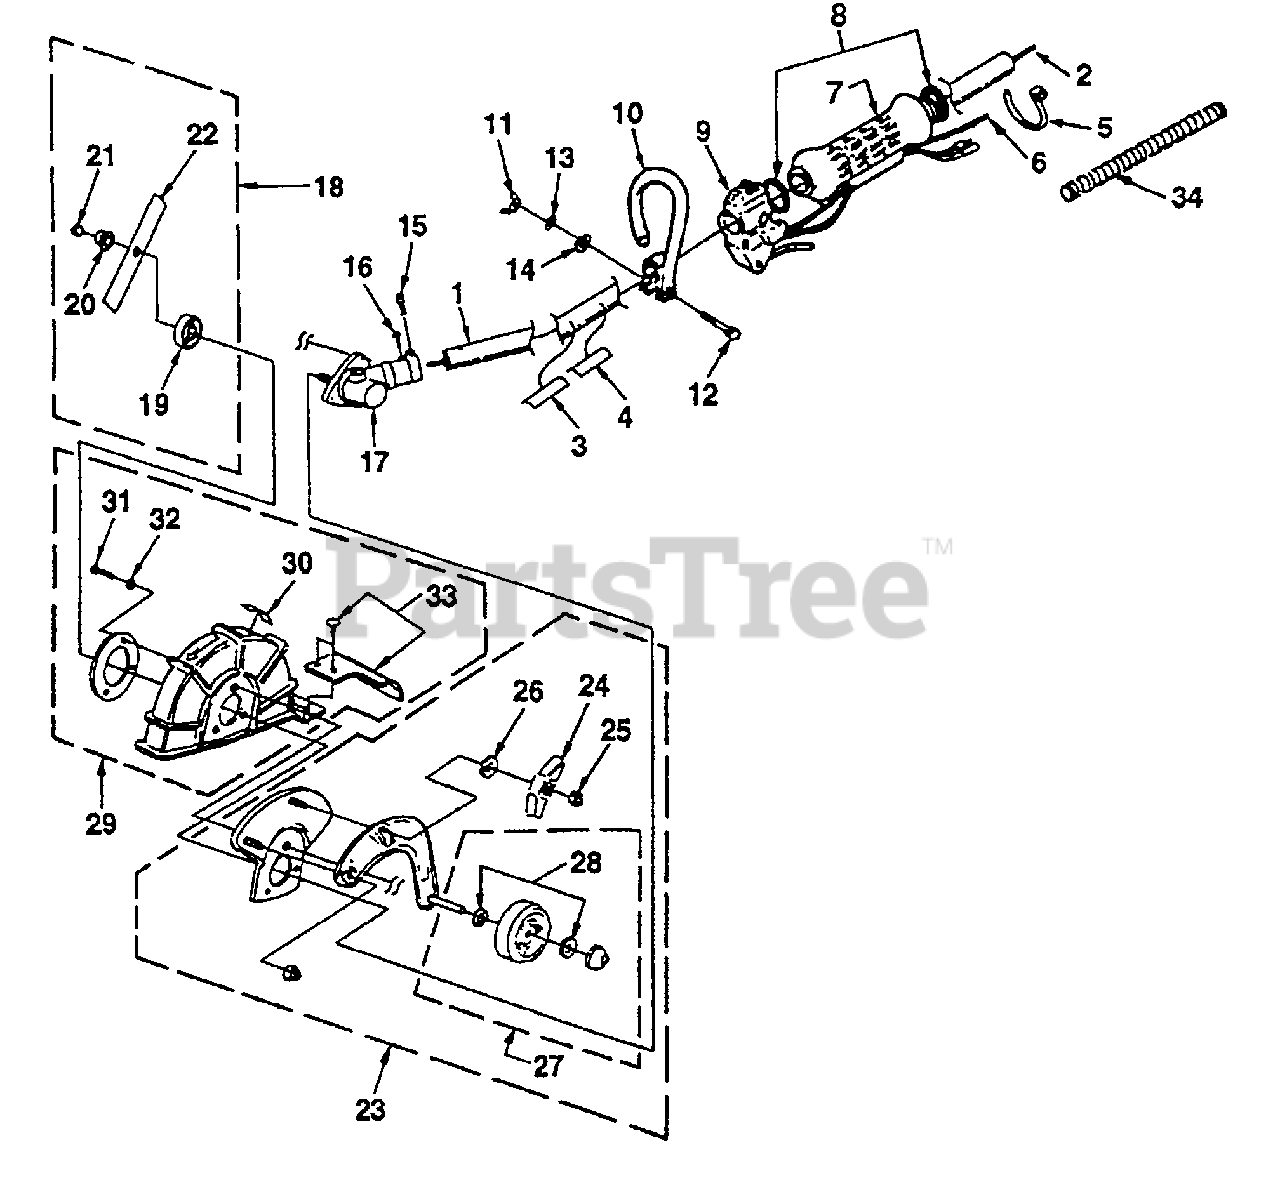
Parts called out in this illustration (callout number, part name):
1	DRIVESHAFT HOUSING
2	SHAFT-Flexible
3	DECAL-Warning
4	DECAL-Start Inst.
5	TIE-Cable
6	THROTTLE CABLE
7	HANDLE GRIP KIT
8	SPRING-Tension
9	THROTTLE & SWITCH
10	HANDLE-Front
11	NUT-Wing
12	SCREW-Cap Hex Hd. (1/4-20 X 2")
13	WASHER-Lock
14	WASHER-Flat
15	SCREW-Cap Socket Hd. (1/4-20 X 7/8")
16	SCREW-Sems Hex Hd. (10-24 X 1/2")
17	GEAR HEAD
18	BLADE KIT
19	WASHER-Flanged
20	WASHER-Flanged (Lower)
21	NUT-Lock
22	BLADE, 2" X 9" (Qty.-2)
23	SUPPORT ARM ASSEMBLY
24	KNOB-Adjusting
25	NUT-Hex
26	WASHER-Flat
27	WHEEL KIT
28	WASHER-Flat
29	GUARD KIT
30	DECAL-Warning
31	SCREW-Hex Hd (10-24 X 5/8")
32	WASHER-Lock (#10)
33	FLAP KIT
34	SLEEVING (Cut length to 10")
